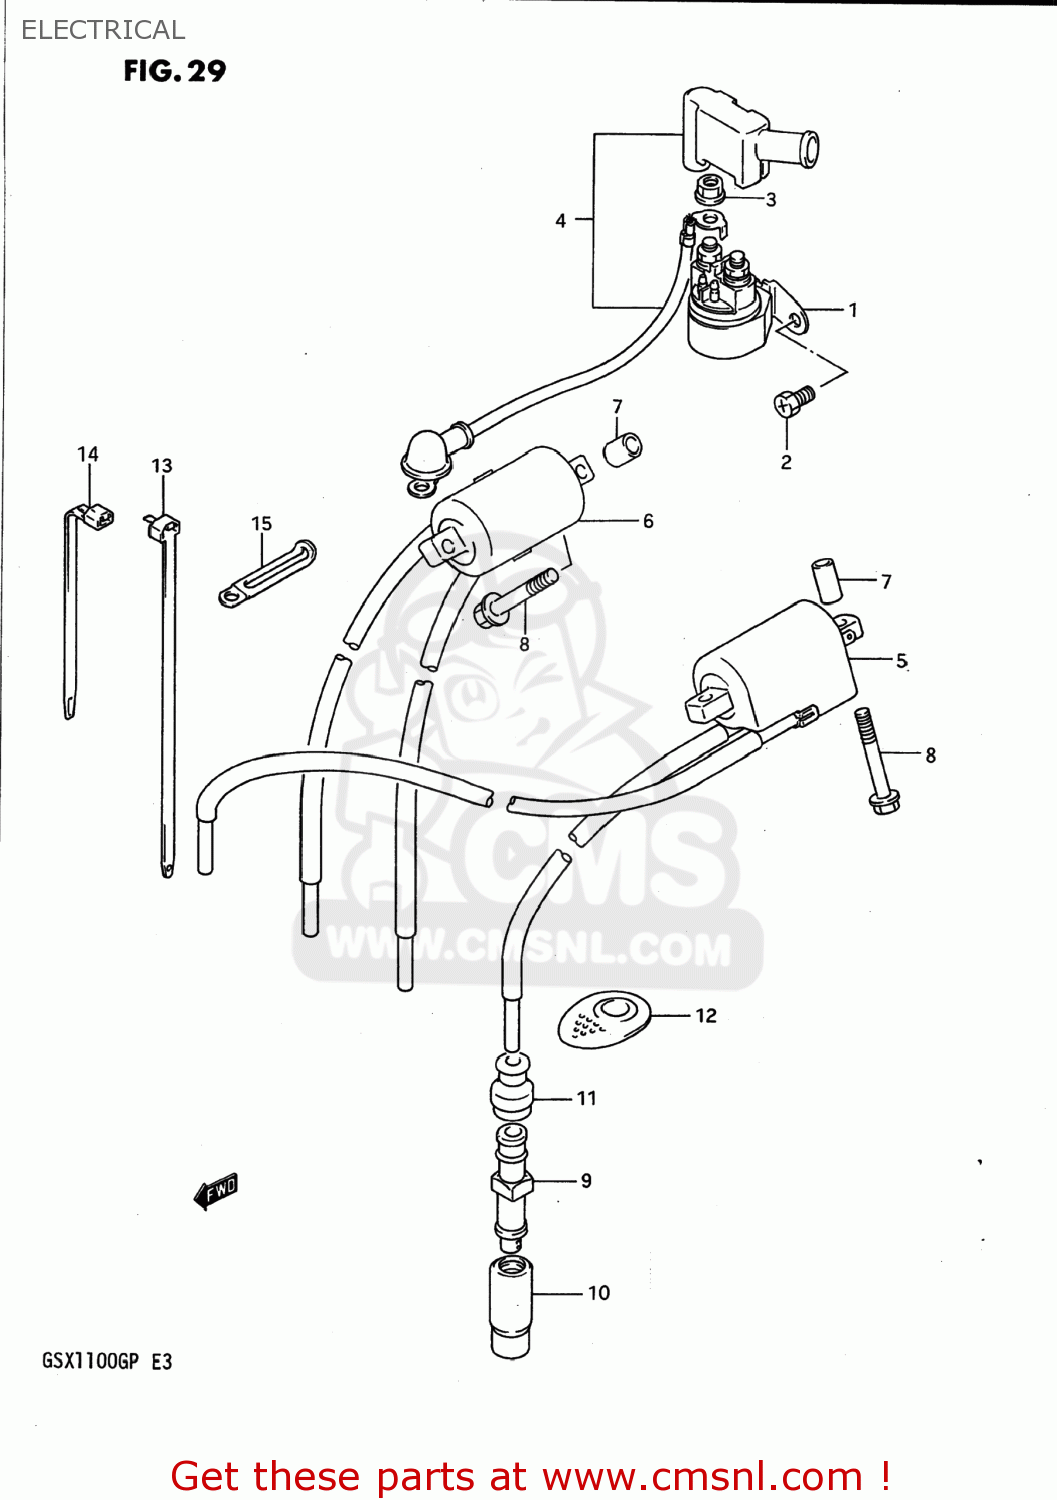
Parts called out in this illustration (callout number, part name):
1	RELAY ASSY,STARTING MOTOR
2	SCREW(6X8)
3	NUT
4	WIRE,STARTER MOTOR LEAD
5	COIL ASSY,IGNITION
6	COIL ASSEMBLY,IGNITION (2
7	SPACER(6.2X12X16)
8	SCREW
9	CAP,SPARK PLUG
10	SEAL,SPARK PLUG
11	SEAL,HIGH TENSION CORD
12	COVER,SPARK PLUG CAP
13	CLAMP
14	CLAMP(L:125)
15	CLAMP
